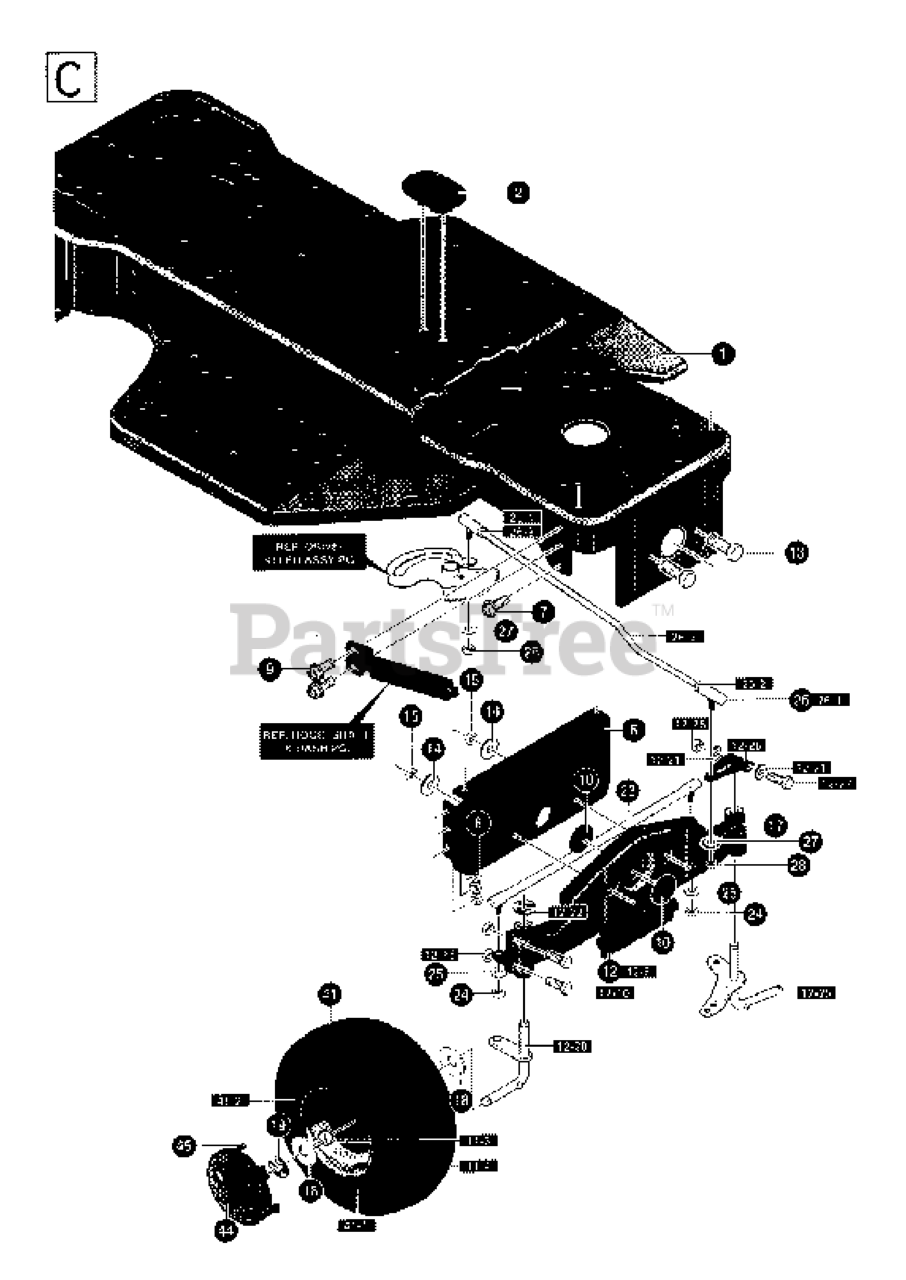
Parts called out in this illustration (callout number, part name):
7	SCREW
9	SCREW
10	PLUG, FRONT AXLE
12-10	SCREW
12-15	NUT
12-21	WASHER, FLAT
12-22	RETAINING RING
12-27	SCREW
12-28	NUT
13	BOLT.HEX.FIN.3/8-16 X 3.GR5
15	NUT
18	WASHER
19	RETAINING RING
24	NUT
25	WASHER 3/8ä
26	ARM
26-1	BALL JOINT
26-2	NUT
27	WASHER 3/8ä
28	NUT
41-1	VALVE STEM
